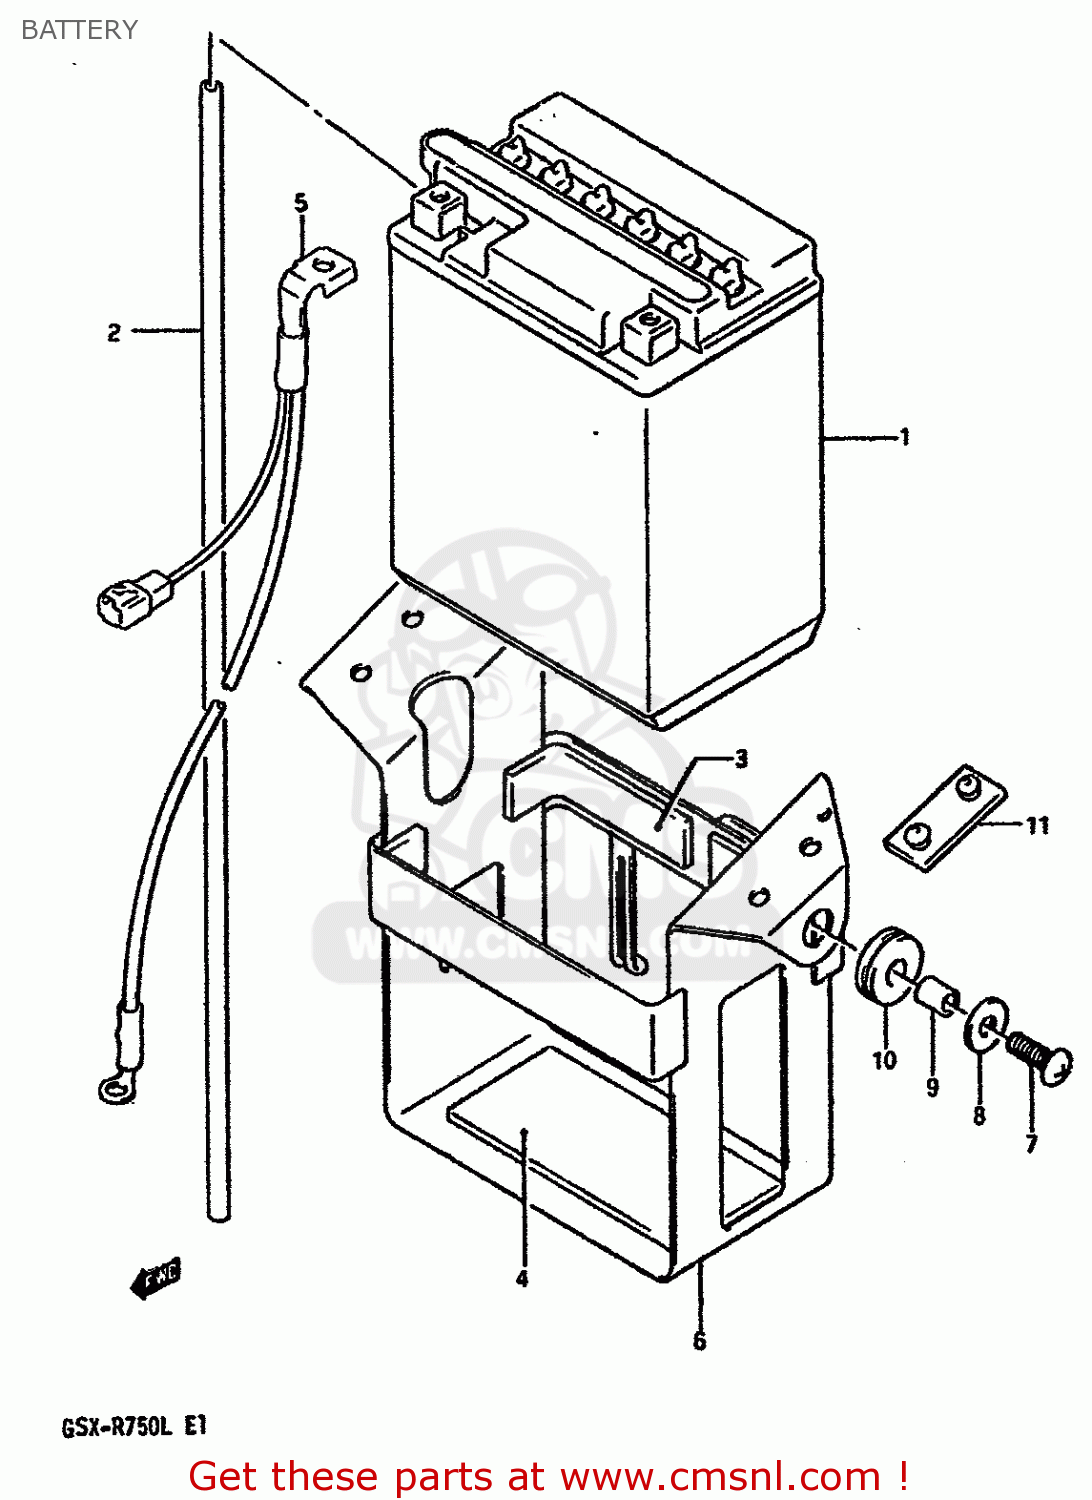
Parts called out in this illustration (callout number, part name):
1	BATTERY ASSY (12V)
2	HOSE,BATTERY EXHAUST
3	PROTECTOR,20X9
4	PROTECTOR(170X95X3.0)
5	WIRE,BATTERY MINUS LEAD
6	HOLDER,BATTERY
7	SCREW
8	WASHER
9	SPACER
10	CUSHION
11	CUSHION
